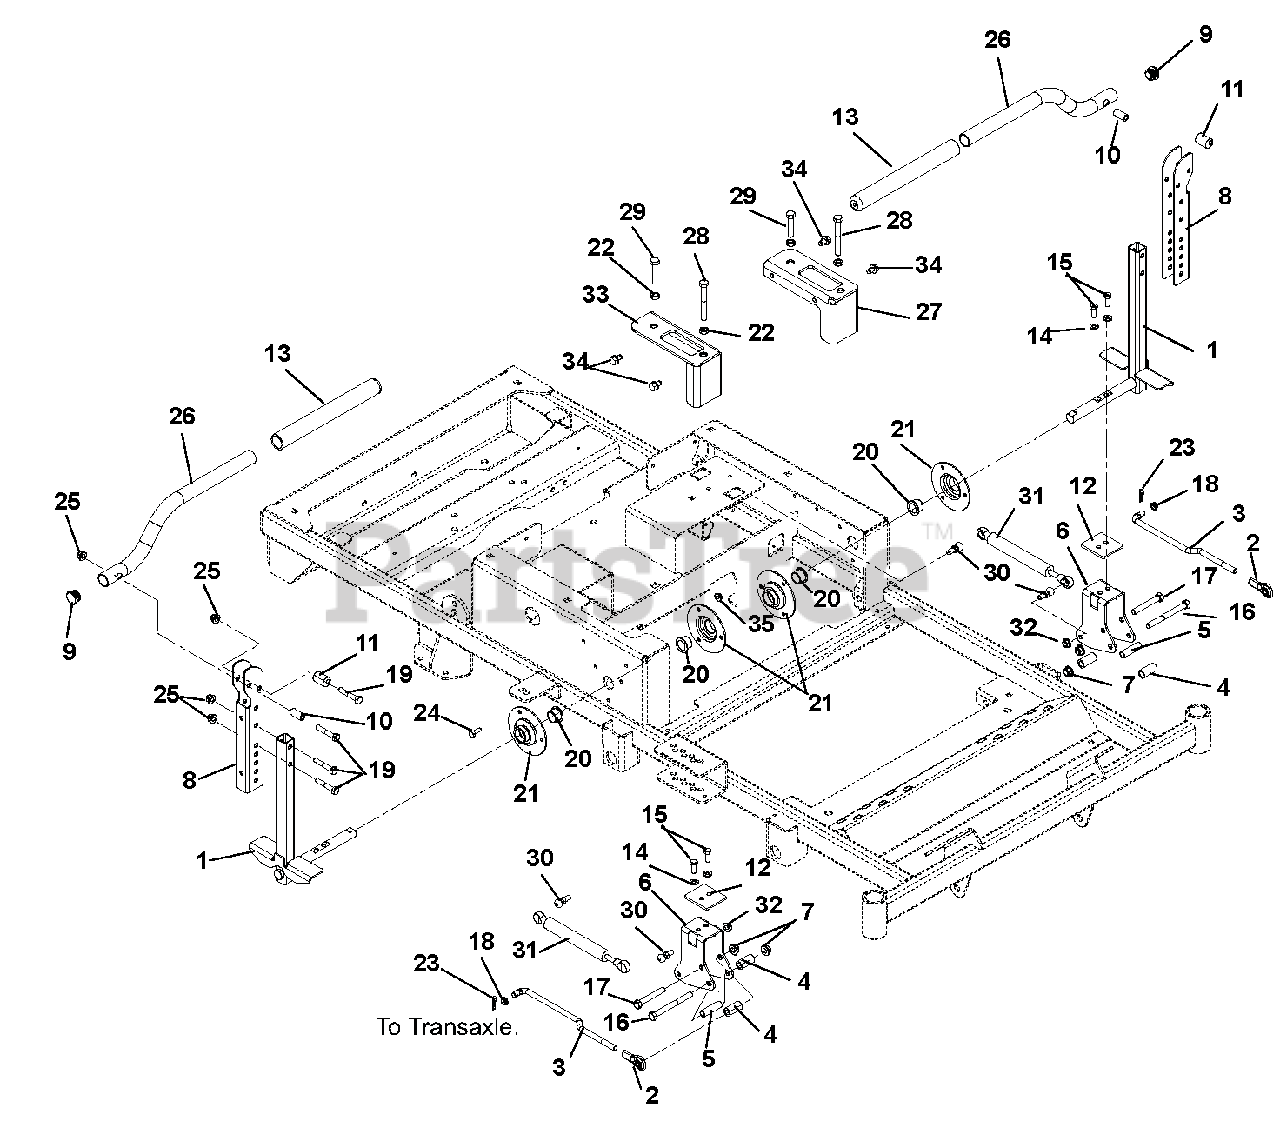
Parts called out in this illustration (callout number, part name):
1	WMT, CONTROL ARM
2	ROD END, .38 RH
3	LINK, TRANSMISSION
4	BSHG, SPCR .390X.625X1.25 PM
5	SPACER, STEERING
6	BRKT, STEERING
7	@NUT-LK-NYL-FLG .38-16 YWZC
8	CHANNEL, UPPER HANDLEBAR
9	CAPLUG, HANDLEBAR
10	BSHG, SPCR .330X.500X1.01 PM
11	BSHG,ECCEN .328X.750X1.01 PM
12	PLATE, STEERING REINFORCING
13	GRIP - HANDLEBAR
14	@WSHR-LK .31X.078 REG YWZC
15	BLT-HEX .31-18X1.00 GR8 YWZC
16	@BLT-HEX .38-16X3.75 GR5 YWZC
17	@BLT-HEX .38-16X2.50 GR5 YWZC
18	BUSHING, POLYLINER-.38 SNAPIN
19	@BLT-HEX .31-18X1.75 GR5 YWZC
20	BSHG-FLG .750X1.000X.625X1.250
21	BEARING FLANGE
22	NUT-HEX-JAM .375-16 YWZC
23	PIN-HAIR INT .08X.18X1.18 YWZC
24	@BLT-HEX .25-20X.75 GR5 YWZC
25	@NUT-LK-NYL-FLG .31-18 YWZC
26	HANDLEBAR, ZTXL
27	BRACKET, LH SPEED CONTROL
28	BLT-HEX .38-16X3.00 GR5 FTH YZ
29	BLT-HEX .375-16X1.750 FTD YWZC
30	STUD- BALL
31	DAMPER, ZT XL
32	@NUT-LK-TOP-FLG .31-18 YWZC
33	BRACKET, RH SPEED CONTROL
34	@SCR-TAP .31-18X.50 HWH TR YWZ
35	@NUT-LK-TOP-FLG .25-20 YWZC
